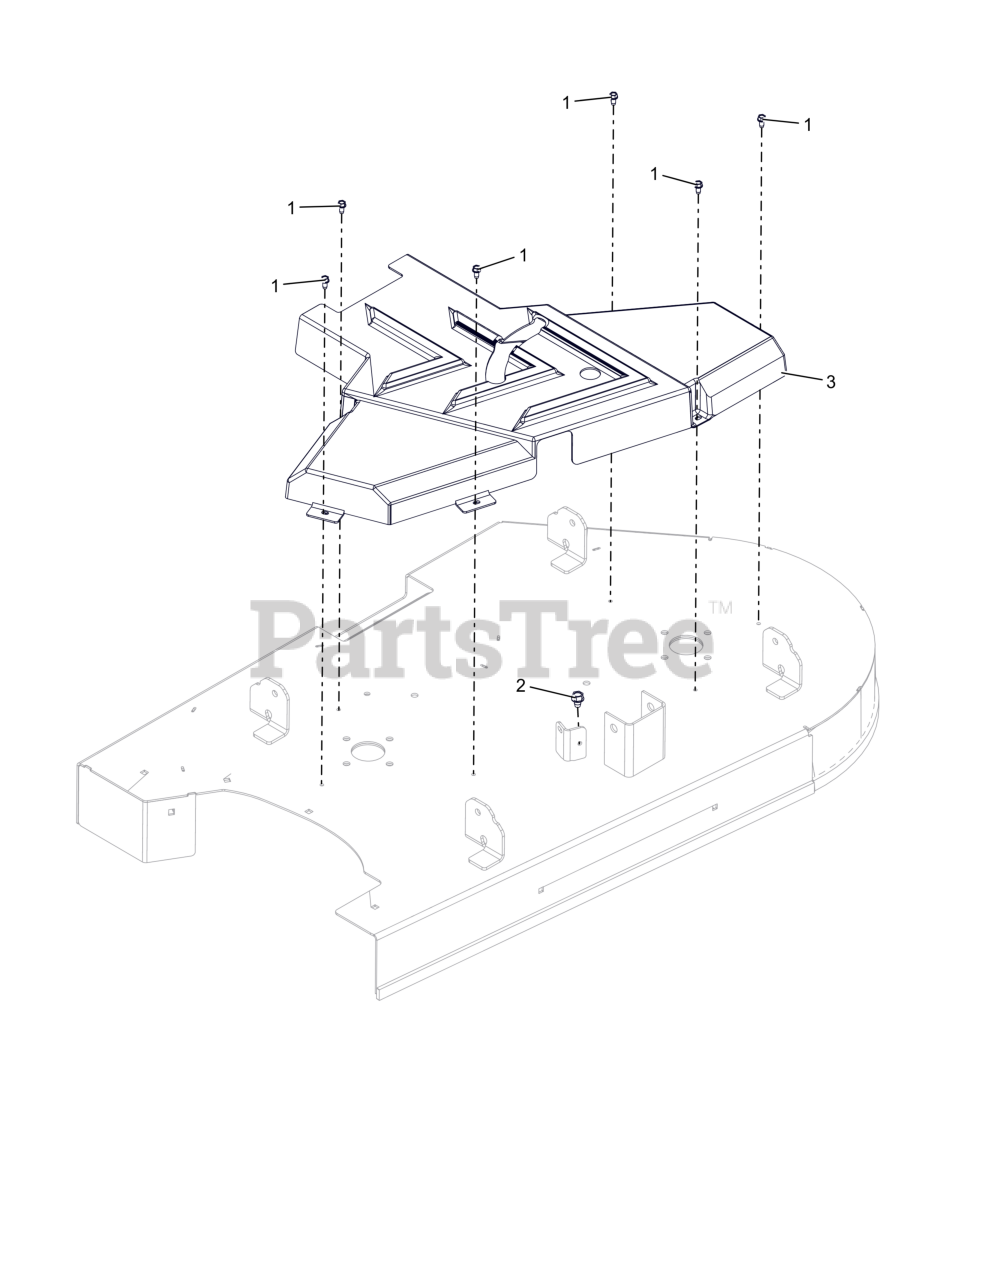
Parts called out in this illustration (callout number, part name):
1	SCR-TAP .25-20X.50 HWH ZCC
2	SCR,TAP .375-16X.50 HWH TR ZCC
3	GUARD, BELT 42" EDGE CE
